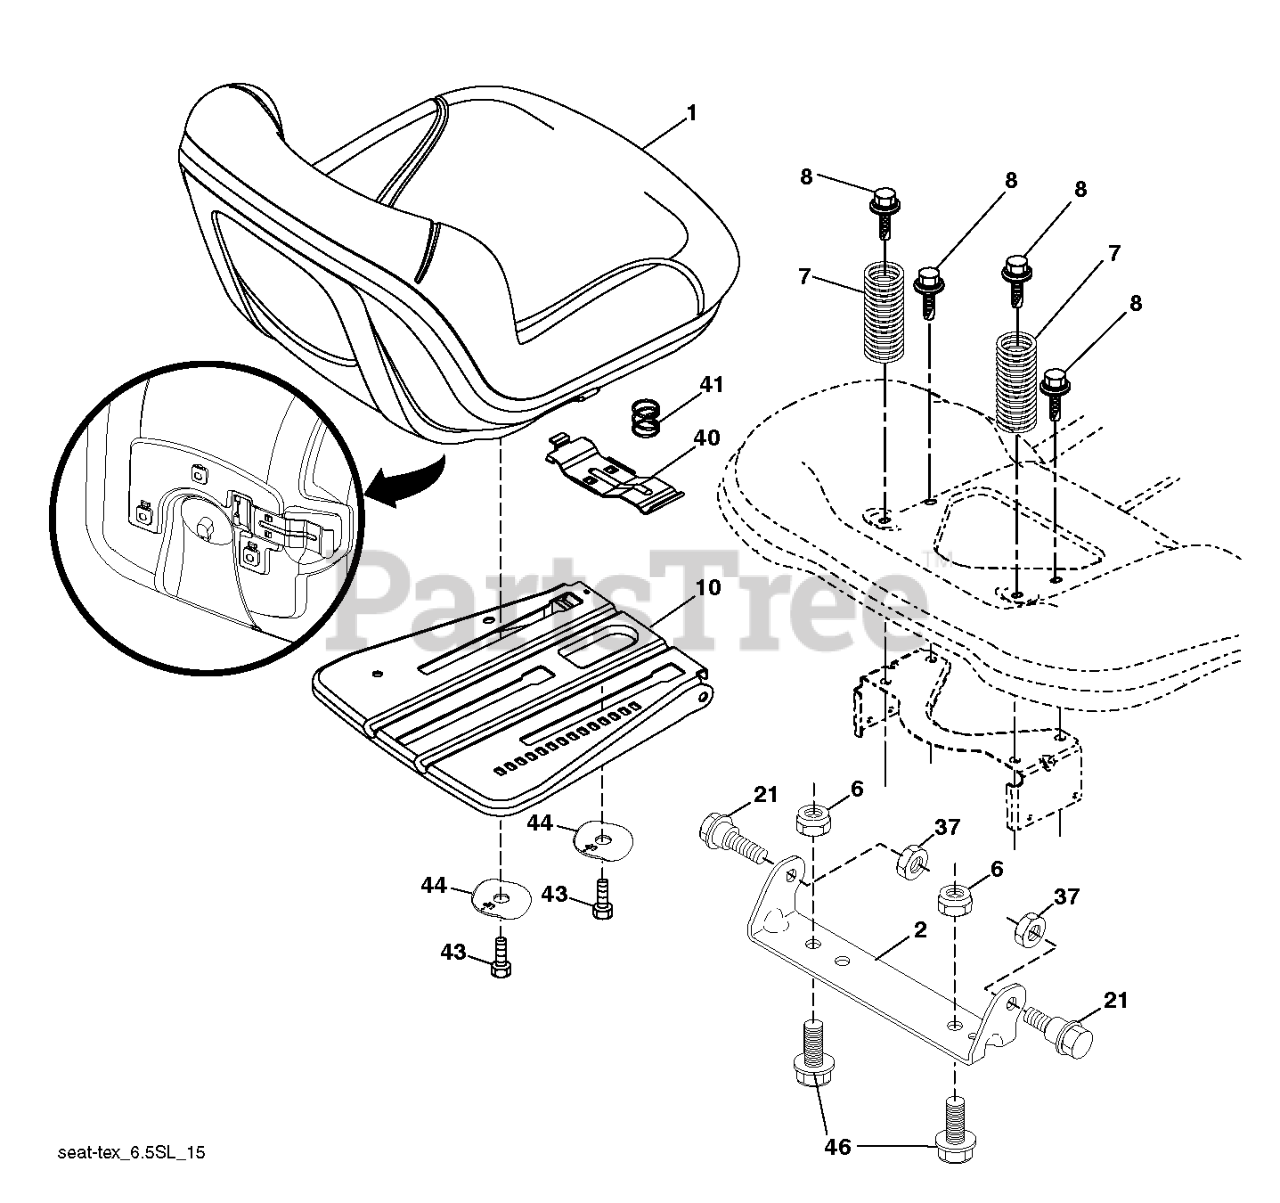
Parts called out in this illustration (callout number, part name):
1	SEAT.TG150.BLK.NLOGO.
2	BRKT.PIVOT.FENDER
6	NUT
7	SPRING.COMPRESS.SEAT.TAPERED
8	BOLT, 5/16-18 X 1 3/4
10	PLATE.PNT.SEAT.SLIDE.3PT.EDIP
21	BOLT.5/16-18X5/8.SHOULDER
37	NUT.71038.31-18.HEX.NYLOCK
40	HANDLE.SLIDE.SEAT.TEX.BLACK
41	SPRING.LATCH.SEAT.TEX
44	WASHER.WINGED.3/8ID.1.5OD
46	BOLT.3/8-16X1;1.25OD.WSHR.SEMS
